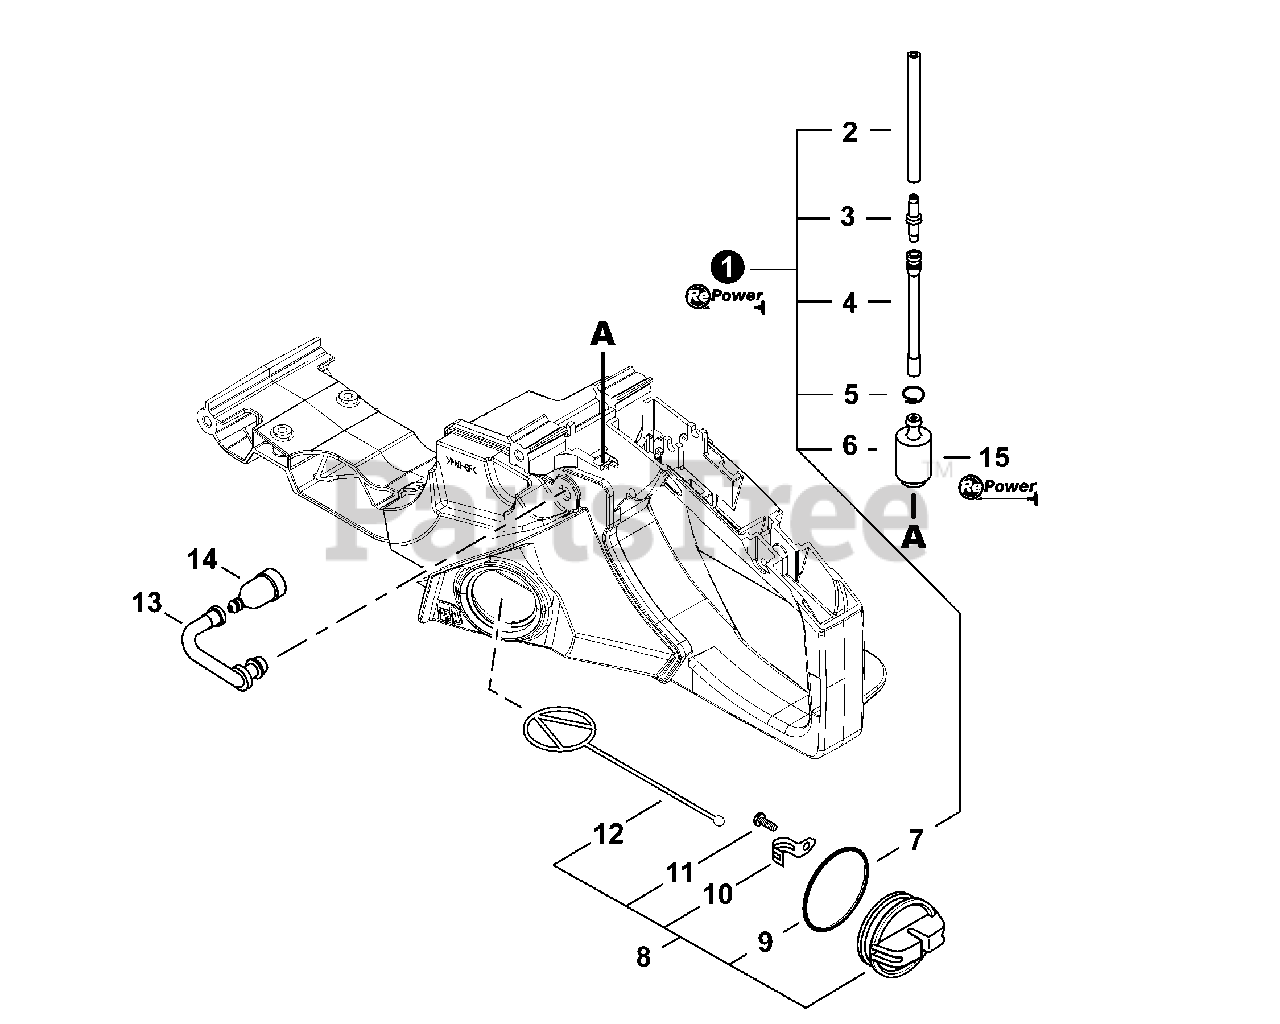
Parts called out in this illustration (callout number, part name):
1	FUEL SYSTEM KIT
2	PIPE, FUEL 3×6×75
3	CONNECTOR, PIPE
4	PIPE, FUEL
5	CLIP Ø6
6	FILTER, FUEL
7	O-RING 29
8	CAP ASSY, FUEL
9	O-RING 29
10	RETAINER, CONNECTOR
11	SCREW, TAPPING 3×8
12	CONNECTOR, CAP L= 60 MM
13	PIPE, FUEL VENT
14	VENT ASSY
15	TUNE-UP KIT - REPOWER
